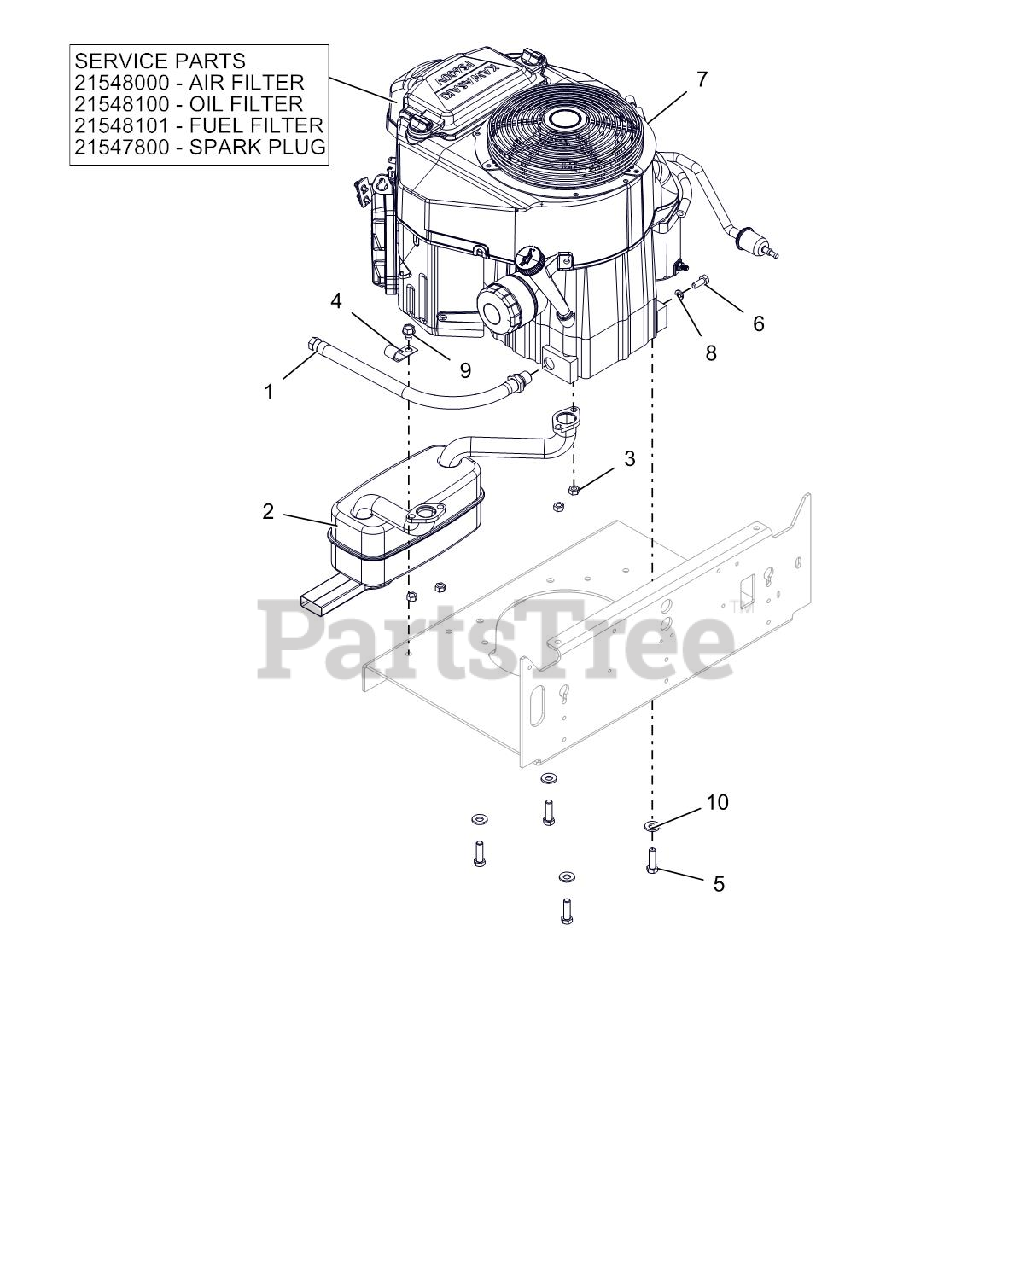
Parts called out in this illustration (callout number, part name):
1	HOSE, OIL DRAIN
2	MUFFLER, KAW FS691/730
3	NUT-LK-TOP M8-1.25 YWZC
5	BLT-HEX.38-16X1.25 G5YZ NYTORQ
6	@BLT-HEX M8-1.25X20 YWZC
7	ENGINE, KAWASAKI FS730
7	AIR FILTER, KAWASAKI FR
7	OIL FILTER, KAWASAKI FR
7	FUEL FILTER-KAWASAKI FR
7	SPARK PLUG, KAWASAKI FR
8	@WSHR-LK .31X.078 REG YWZC
9	@SCR-TAP .38-16X.50 HWH TR YWZ
10	WASHER, 3/8" SPRING DISC
